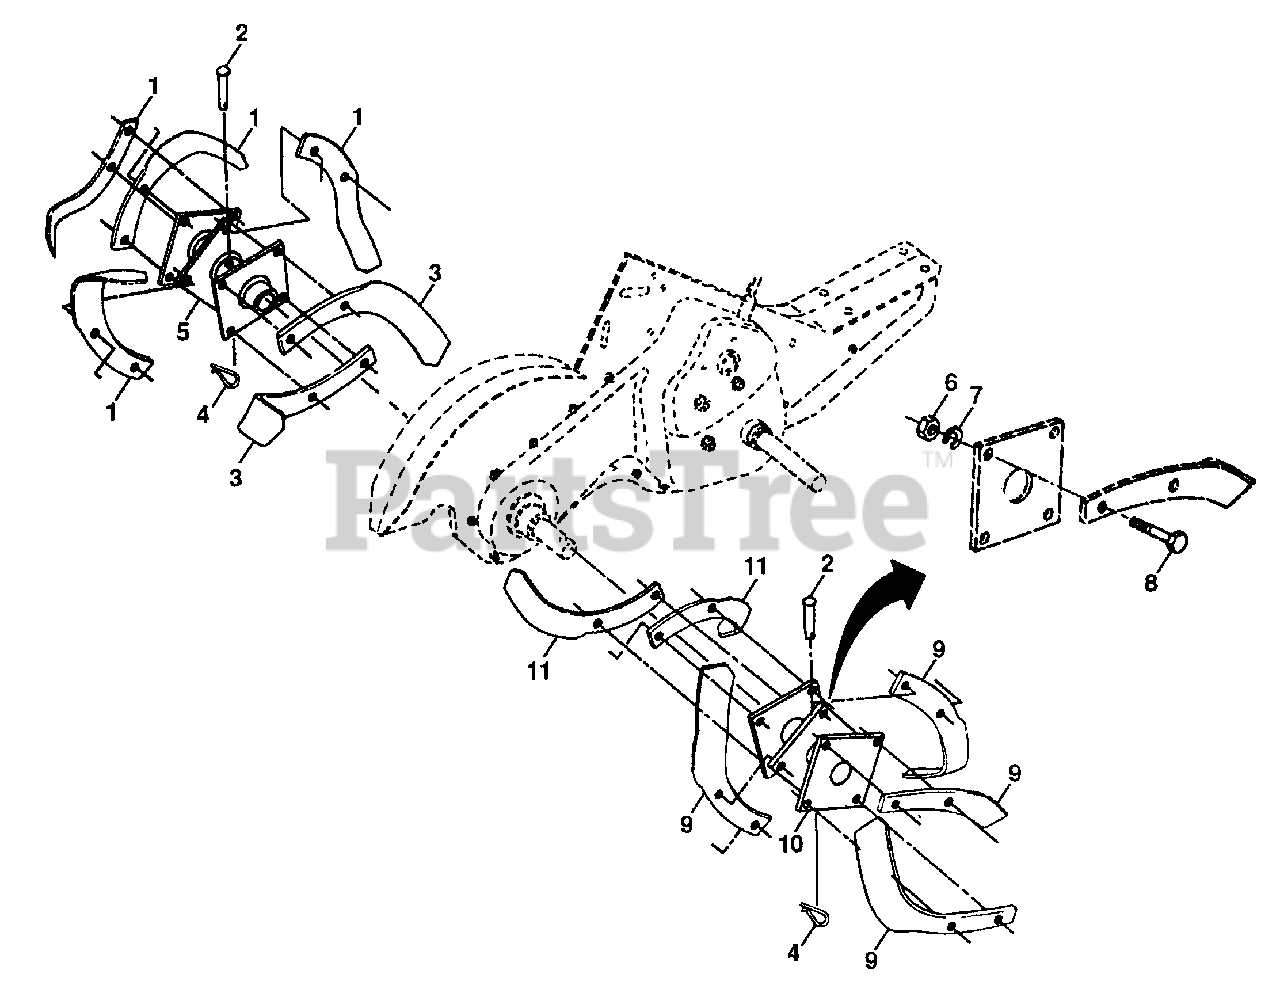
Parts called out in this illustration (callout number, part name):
1	Tine, Outer, L.H. (AYP part number)
2	Clevis Pin
3	Tine, Inner, L.H.
4	Clip, Hairpin (AYP part number)
5	Assembly, Hub and Plate, L.H.
6	Nut, Hex 3/8-24
7	Washer, Lock 3/8
8	Bolt, Hex 3/8-24 x 1
9	Tine, Outer, R.H. (AYP part number)
10	Assembly, Hub and Plate, R.H.
11	Tine, Inner, R.H.
